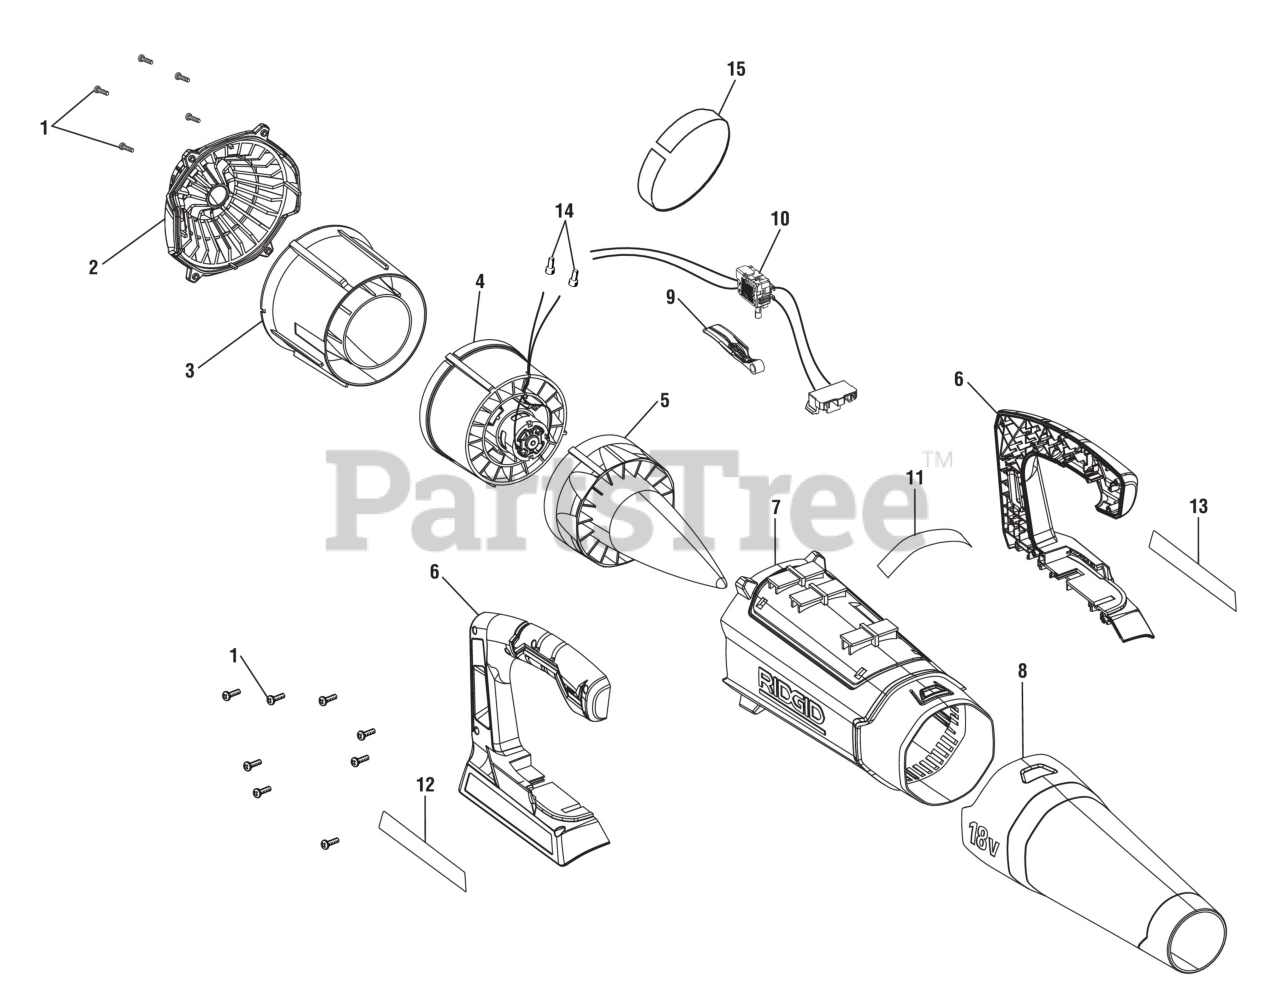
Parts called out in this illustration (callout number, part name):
3	Airflow Rectifier - Rear
4	Motor Blower Assembly
5	Airflow Rectifier - Front
6	Handle Assembly
7	Motor Housing
8	Blower Nozzle
10	Switch & Contact Plate Assembly
11	Icon Label
12	Warning and Data Label
13	Logo Label
14	Wire Connector
